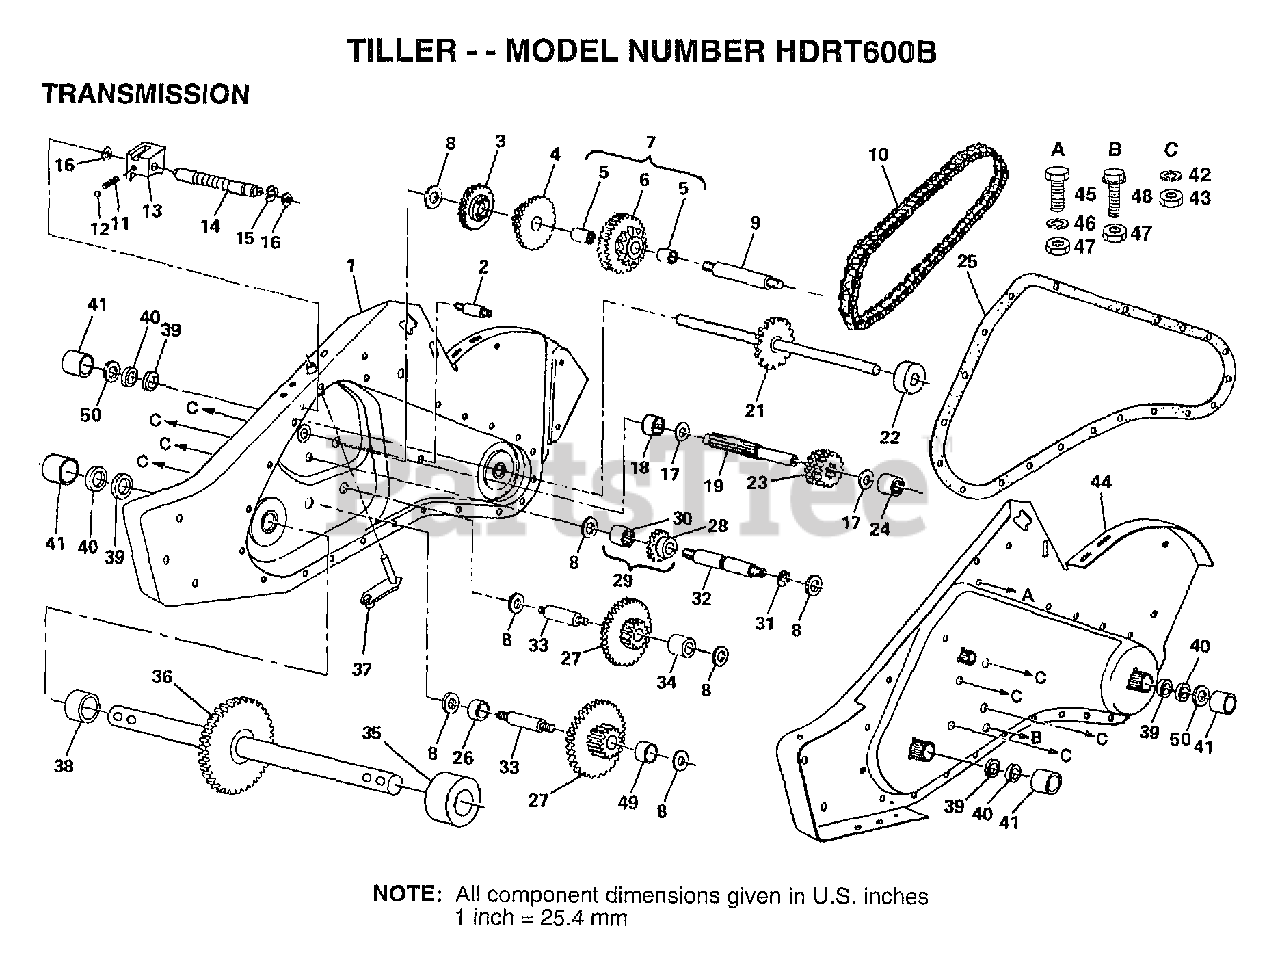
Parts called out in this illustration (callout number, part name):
2	BOLT TI
3	REVERSE GEAR TI
4	CLUSTER GEAR TI
5	"CRT, BEARING"
7	SPROCKET ASSY TI
8	WASHER
9	REDUCTION SHFT TI
10	CHAIN TI
11	SPRING-SHIFT CRT
13	SHIFT FORK TI
14	SHIFT SHAFT TI
15	KLIP RING
16	WASHER SEAL CRT
17	"T, BEARING"
18	"TI, BEARING"
19	SHAFT INPUT T
21	SHAFT TINE CRT
22	SPACER CRT
23	INPUT PINION TI
24	NEEDLE BRNG LT
25	GEARCASE GSKT TI
26	SPACER CRT
27	GEAR CLUSTER CRT
28	REVERSE GEAR TI
29	GEAR ASSY TI
30	NEEDLE BEARING TI
31	KLIP RING
32	REVERSE SHAFT TI
33	SHAFT CRT
34	SPACER CRT
35	SPACER CRT
36	SHAFT ASSY CRT
37	BRACKET ASM SHIFT
38	SPACER CRT
39	OIL SEAL STD
40	SEAL RING RUBBER
41	CUP.FORMED.
42	LOCKWASHER
43	NUT.ASF.HEX.7/16
45	BOLT
46	LOCKWASHER
47	NUT.HEX.5/16-18
48	BOLT TI
49	SPACER CRT
50	RING SPIRAL CRT
